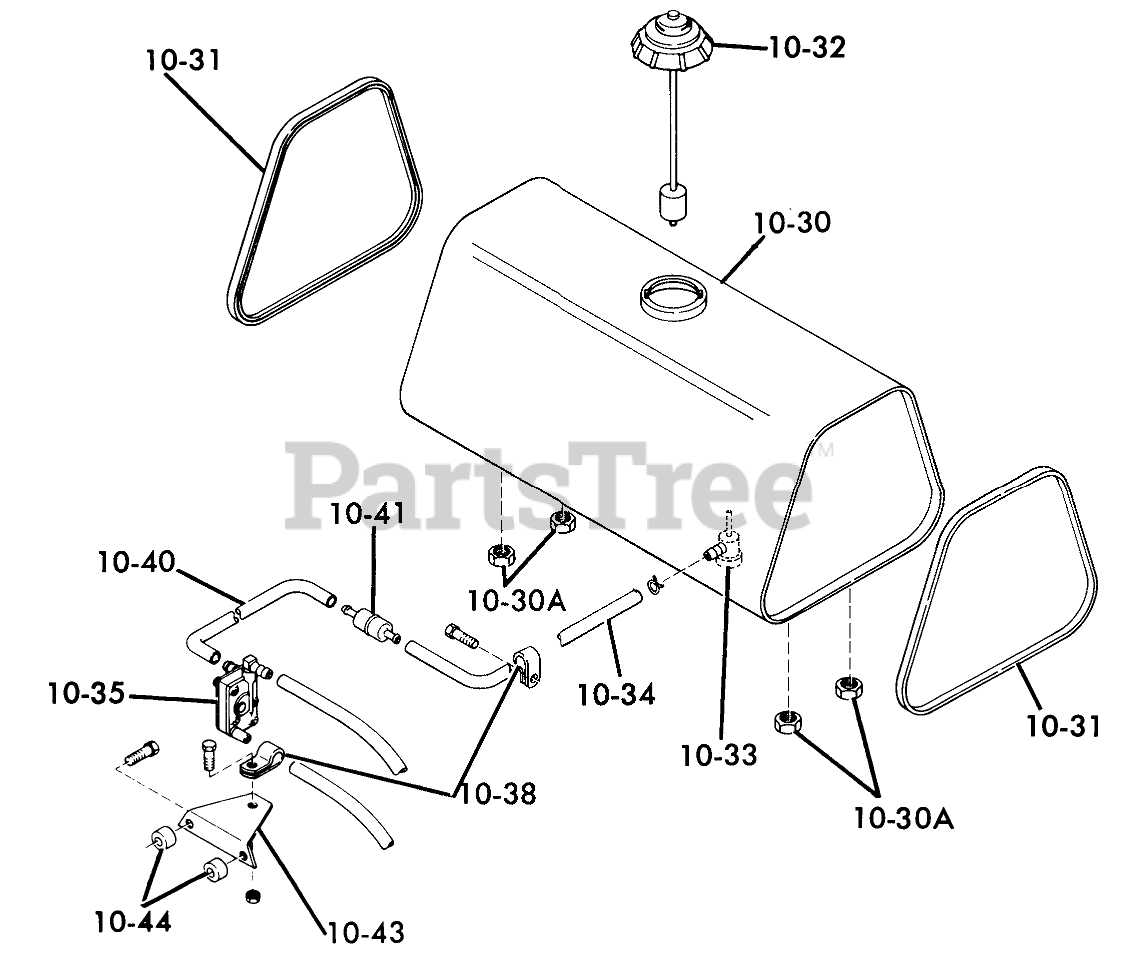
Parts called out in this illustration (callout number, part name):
10-01	Screw, Special
10-02	Handle Throttle
10-03	Screw
10-03A	SPACER CLUTCH ARM
10-04	FRICTION WASHER
10-05	WASHER-SPRING DISC
10-06	NUT
10-06A	Bolt
10-06A	Washer-3/8
10-07	Rod-Throttle
10-07A	Rod-Throttle
10-07A	Cotter Pin 3/32 X 1/2
10-08	BALL JOINT ASSY R
10-09	Screw, Special
10-09	Assy-Bracket
10-10	HANDLE
10-11	Screw
10-12	FRICTION WASHER
10-13	WASHER-SPRING DISC
10-14	CABLE CHOKE CONTROL
10-14	NUT
10-16	HEX NUT 10-32 E.S.
10-16	CLIP BOWDEN WIRE
10-16	Screw
10-17	THROTTLE CONTROL CLP
10-20	Starter Wire Clip
10-20	Bracket
10-20	ASSY-MUFFLER
10-20	Screw
10-21	ASSY-MUFFLER CLAMP
10-22	Nipple
10-22A	NIPPLE-EXHAUST 1X4
10-22A	Nipple-1" x 6"
10-23	Nipple 2 1/2 in. Long
10-24	Nipple 5 in. Long
10-25	ELBOW
10-26	Fitting Exhaust RH
10-26	Fitting Exhaust LH
10-26	Bolt
10-26	HHCS
10-26	Lockwasher
10-27	TUBE-INLET
10-30	Fuel Tank
10-30A	Flanged Nut
10-31	Edge Trim
10-32	GAUGE CAP
10-32	Cap-Tank
10-33	FILTER & VALVE ASSY
10-34	Fuel Line 62
10-34	Fuel Hose-Tank To Filter
10-34	CLAMP CORBIN 7/16
10-35	Pump Fuel
10-36	Coupling
10-37	FITTING STRAIGHT
10-37	Bolt
10-38	CLAMP-HOSE
10-38	Bolt
10-38	Nut
10-40	Hose
10-40	CLAMP CORBIN 7/16
10-40A	Skid Bracket
10-41	Filter
10-41	CLAMP CORBIN 7/16
10-43	Bracket
10-44	Spacer
10-44	Clamp
